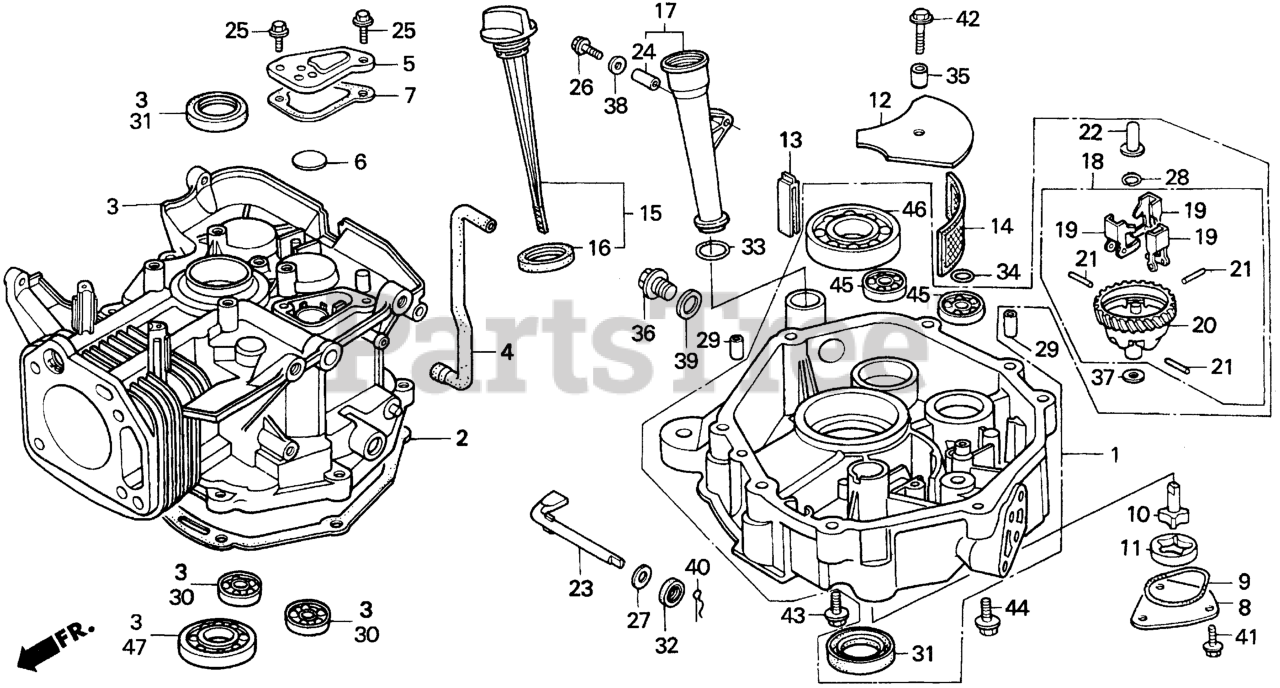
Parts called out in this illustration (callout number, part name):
1	PAN ASSY., OIL
2	GASKET, OIL PAN
3	CYLINDER ASSY.
4	TUBE, BREATHER
5	CAP, BREATHER CHAMBER
6	VALVE, BREATHER
7	GASKET, BREATHER CAP
8	COVER, OIL PUMP
9	O-RING, PUMP COVER
10	ROTOR (INNER)
11	ROTOR, OIL PUMP (OUTER)
12	PLATE, OIL FILTER
13	RUBBER, OIL RETURN
14	SCREEN, OIL FILTER
15	CAP ASSY., OIL FILLER
16	GASKET, OIL FILLER CAP
17	EXTENSION, OIL FILLER
18	GOVERNOR ASSY.
19	WEIGHT, GOVERNOR
20	HOLDER, GOVERNOR WEIGHT
21	PIN, GOVERNOR WEIGHT
22	SLIDER, GOVERNOR
23	SHAFT, GOVERNOR ARM
24	COLLAR, EXTENSION Use up to Engine SN 1257294.
25	BOLT, FLANGE (6X12) (CT200)
26	BOLT, FLANGE (6X35)
27	WASHER, THRUST (8.1MM)
28	CLIP, GOVERNOR HOLDER
29	PIN, DOWEL (8X12)
30	BEARING, RADIAL BALL (6202)
31	OIL SEAL (35X52X8)
32	OIL SEAL (8X14X5)
33	O-RING (22.5X2.2) Use from Engine SN 1257295.
34	O-RING (11.8X2.4)
35	COLLAR, OIL FILTER SETTING
36	BOLT, DRAIN PLUG (20MM)
37	WASHER, PLAIN (6MM)
38	WASHER, PLAIN (6MM)
39	WASHER, DRAIN PLUG (20MM)
40	PIN, LOCK (10MM)
41	BOLT, FLANGE (6X12) Use up to Engine SN 1543277.
42	BOLT, FLANGE (6X25)
43	BOLT, FLANGE (8X40)
44	BOLT, FLANGE (8X60)
46	BEARING, RADIAL BALL (6207)
47	BEARING, RADIAL BALL (6207)
